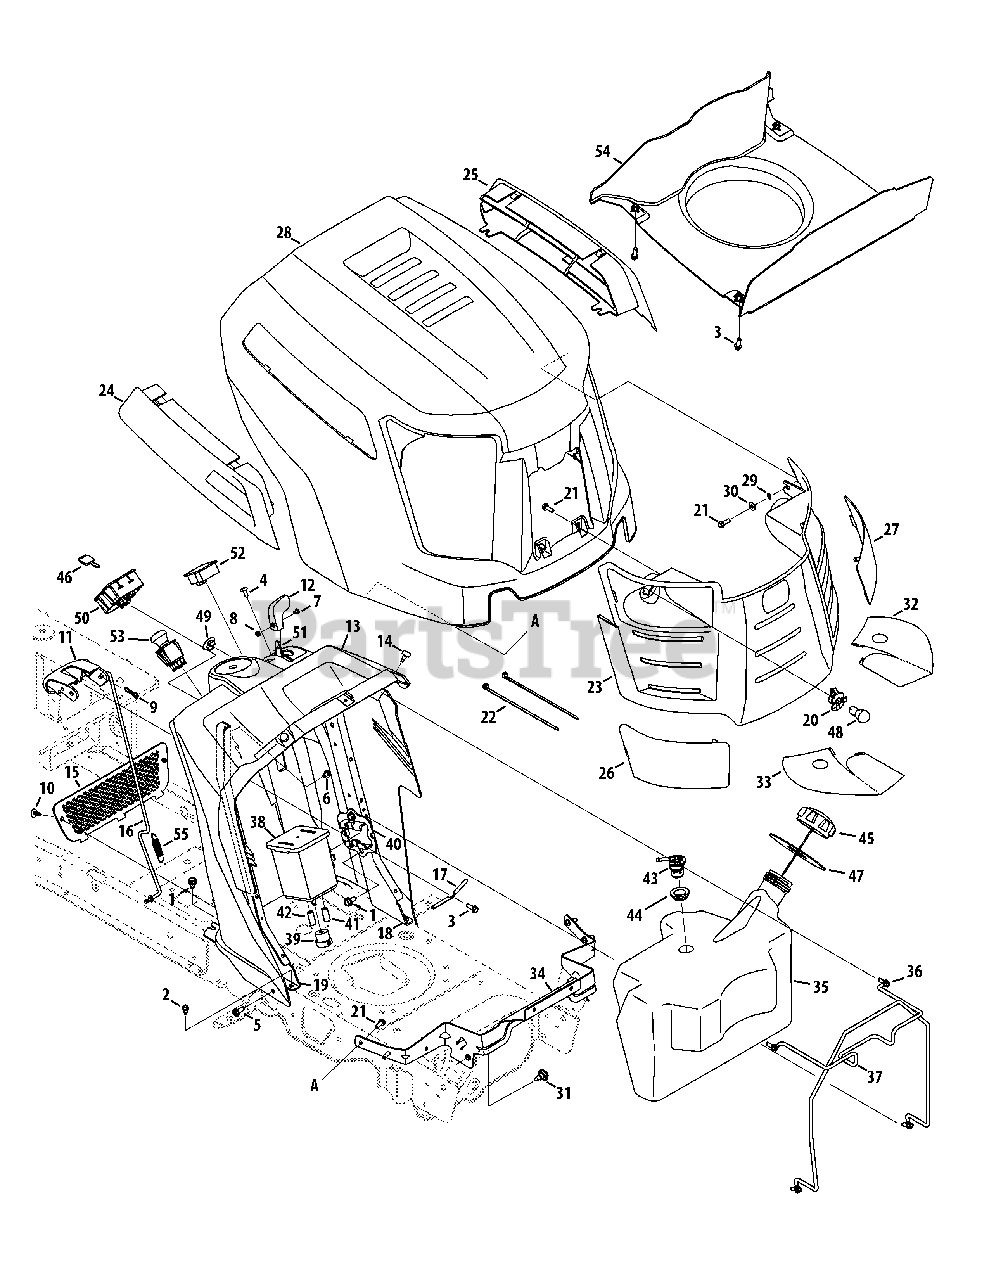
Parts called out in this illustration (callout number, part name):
1	Screw, Self-tapping, 5/16-18, .750
2	Screw, Self-tapping, 1/4-20, 0.500
3	Screw, HL, 1/4-15, 0.750
4	Screw, Ab, 1/4-14, 0.625,
5	Screw, Self-tapping, 5/16-18, 0.750,
6	Screw, Self-tapping, 1/4-20 x .625
7	Screw, Mach, #8-32, 0.375
8	Nut, Hex, #8-32
9	Pin, Cotter, Bow-Tie 72
10	Clip, Ratchet, .250 Dia
11	Lever, Dash, Cruise/Brake
12	Knob, Throttle
13	Dash Panel, A-Style, Elect PTO
14	Bumper, .62 Dia X .3
16	Rod, Control, Latch Cub
17	Rod, Lever, Bent
18	Support, Dash, Plate LH
19	Support, Dash, Plate RH
20	Socket, Lamp
21	Screw, 1/4 Dia, .750
22	Tie, Cable, Push Mount 7.5 Lg
23	Grille Ass’y (Incl. 26, 27, 32 & 33)
24	Scoop, Hood, RH A-Style
25	Scoop, Hood, LH A-Style
26	Lens, Hood, RH A-Style
27	Lens, Hood, LH A-Style
28	Hood, A-Style
29	Washer, Lock, 1/4, External
30	Washer, Flat, .271, .630, .065
31	Screw, Shoulder, .43x.29, 5/16-18
32	Reflector, Cub A Style, LH
33	Reflector, Cub A Style, RH
34	Bracket, Pivot, Hood A-Style
35	Tank, Fuel, 3.30 Gal.
36	Screw, Self-tapping, 1/4-20, .75
37	Rod, Support, Fuel Tank
38	Canister, Carbon, 5 Gallon (CA)
39	Filter, Vent, Canister (CA)
40	Bracket, Adapter, Canister (CA)
41	Hose, Fuel, Low Perm, 3/16 Wht (CA)
42	Hose, Fuel, Low Perm, 7/32 Yel (CA)
43	Valve, Rollover Grommet
44	Grommet, Rubber, 23.0 ID
45	Cap, Fuel
46	Key, Ignition
47	Gasket, Fuel Tank
48	Lamp, 12v
49	Plug, Choke
49	Control, Choke, 40.5 x 2, Yellow
50	Module Switch, Ignition
51	Cable, Throttle/Choke, 38"
51	Cable, Throttle, 38"
52	Meter, Indicator
53	Switch, Electric PTO, Yellow
54	Plenum, A-Style
55	Spring, .500 Dia. x 2.733
